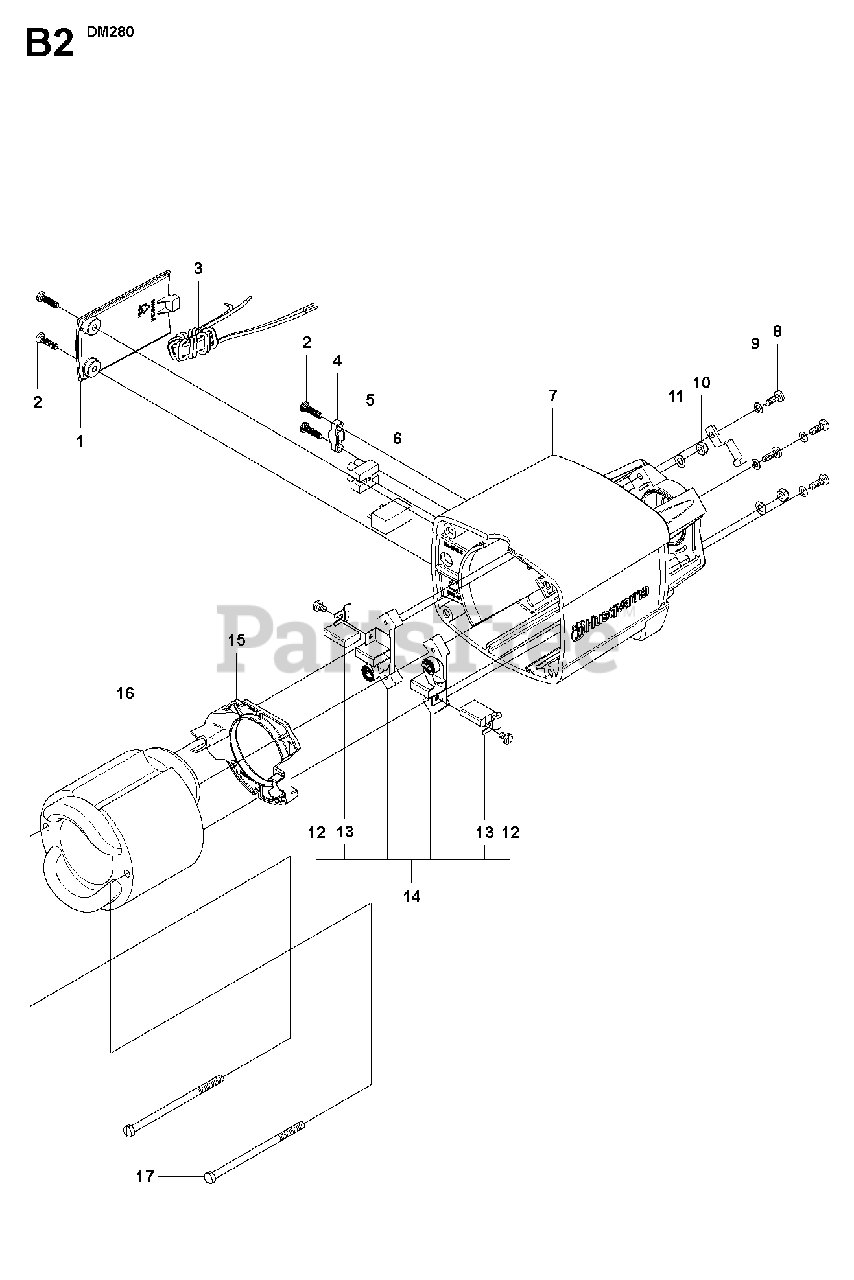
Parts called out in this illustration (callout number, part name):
9	SPRING WASHER
11	SPRING WASHER
12	SCREW SLPANM
13	CARBON BRUSH
14	BRUSH HOLDERIncl. 12 - 13
16	STATOR ASSY110V
16	STATOR ASSY230V
